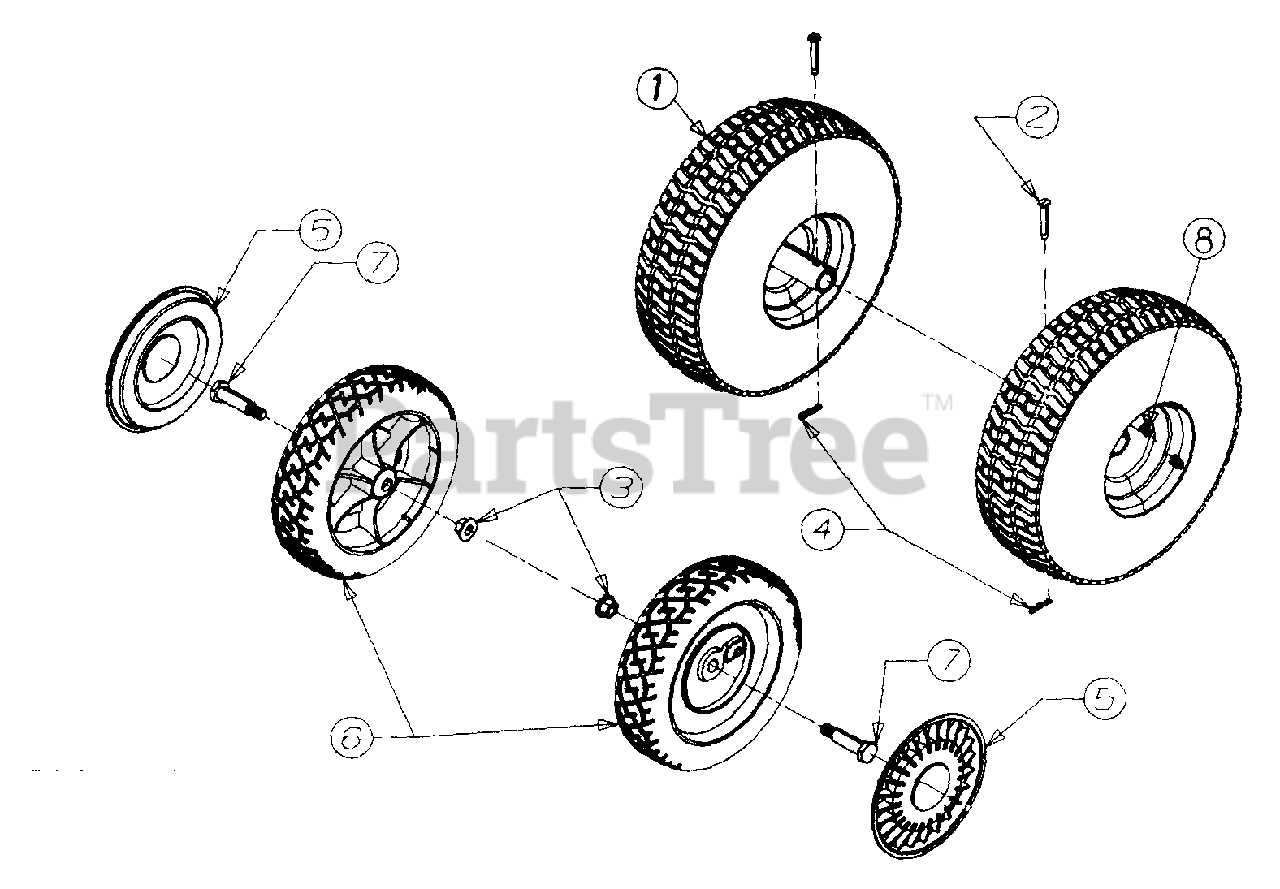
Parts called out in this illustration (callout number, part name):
1	WHEEL ASSY COMPLETE 4" X 10"
2	PIN-CLEVIS
3	NUT-HEX FLANGE
4	PIN-COTTER
5	HUB CAP
6	WHEEL 2" X 8"
7	SCREW-SHOULDER
8	VALVE STEM
